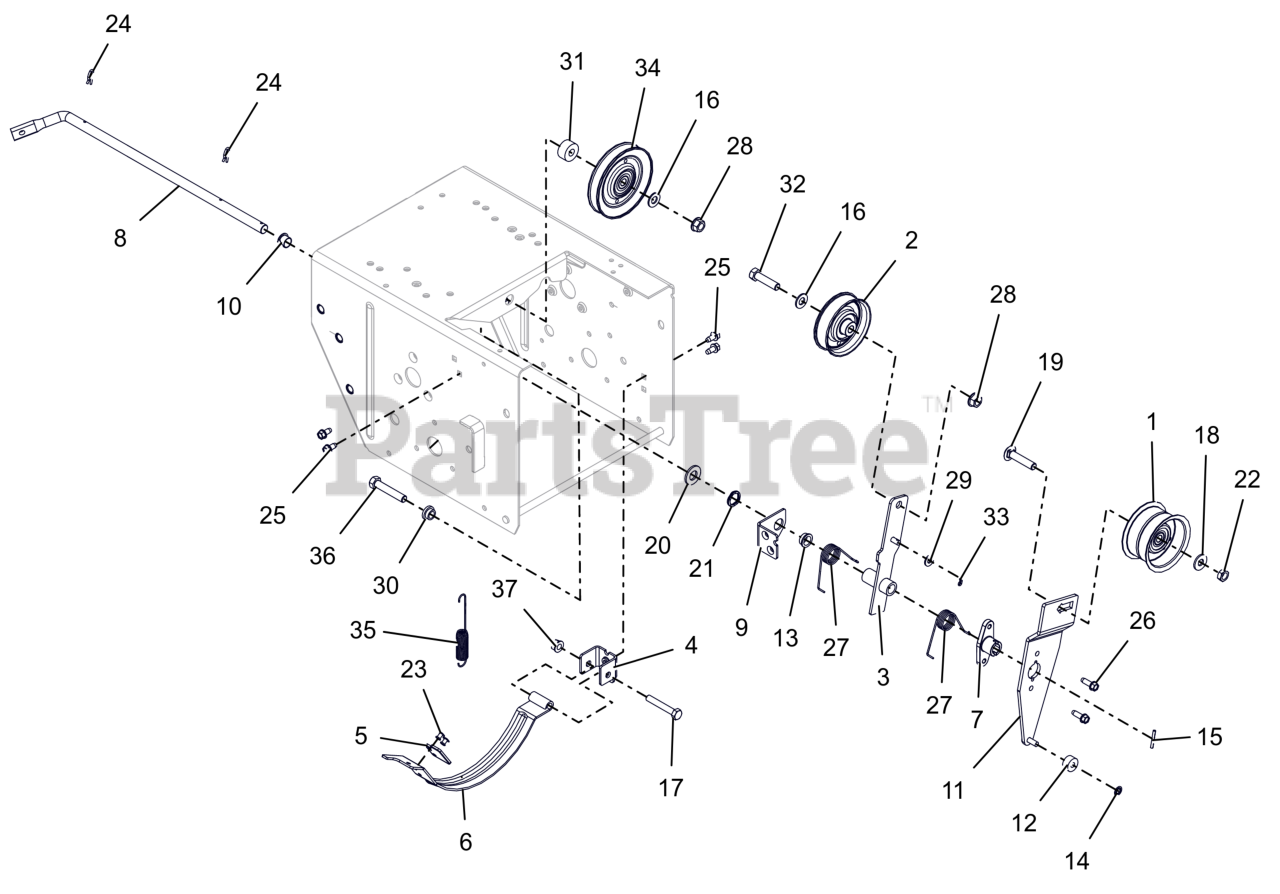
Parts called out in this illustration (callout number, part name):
1	IDLER, FLANGE -2.75 OD X .375 ID
2	IDLER, FLAT - 3.05" X .75"
3	ARM, TRACTION CLUTCH
4	PIVOT, BRAKE
5	PAD, BRAKE
6	ARM, BRAKE-ATTACHMENT
7	HUB, BRAKE ARM
8	ARM, ATTACHMENT
9	BRACKET, SUPPORT
10	BUSHING, POLYLINER-.50 SPLIT
11	ARM, IDLER - ATTACHMENT
12	BSHG,SLV .265 X .625 X .375
13	BSHG,FLANGE .500X.625X.270X.75
14	RG-RTNG-EXT .250X.010
15	PIN-ROLL .125X1.00
16	WSHR,FLT .406X.812X.065 ZCC
17	BLT, HEX .31-18X2.00 G5 ZCC
18	WSHR,FLT .375X.875X.083 ZCC
19	BLT, RHSSN .38-16X1.75 G5 ZCC
20	WSHR,FLT .531X1.062X.095 ZCC
21	WAVE SPRING .600X.875X.25FH
22	NUT-LK-CTR-JAM .375-16 GB ZCC
23	RVT, POP .1875 ZCC
24	CLIP, SPRING
25	SCR-TAP .25-20X.50 HWH ZCC
26	SCR,TAP .25-20X.75 HWH TR ZCC
27	SG-TORS .067X.88
28	NUT-LK-TOP-FLG .38-16 ZC120
29	WSHR,FLT .281X.625X.065 ZCC
30	BSHG, FLANGE .391X.56X.313X.75
31	BSHG,POCKET .391X.570X1.0X.450
32	BLT, HEX .38-16X1.50 G5 ZCC
33	PIN, HAIR #178 .06X.77 ZCC
34	SHV, .38"ID X 4.00"OD V-IDLER
35	SG-TENS .056X.60X4.40
36	BLT,HEX .38-16X2.00 G5 ZCC
37	NUT-LK-TOP-FLG .312-18 GF ZCC
